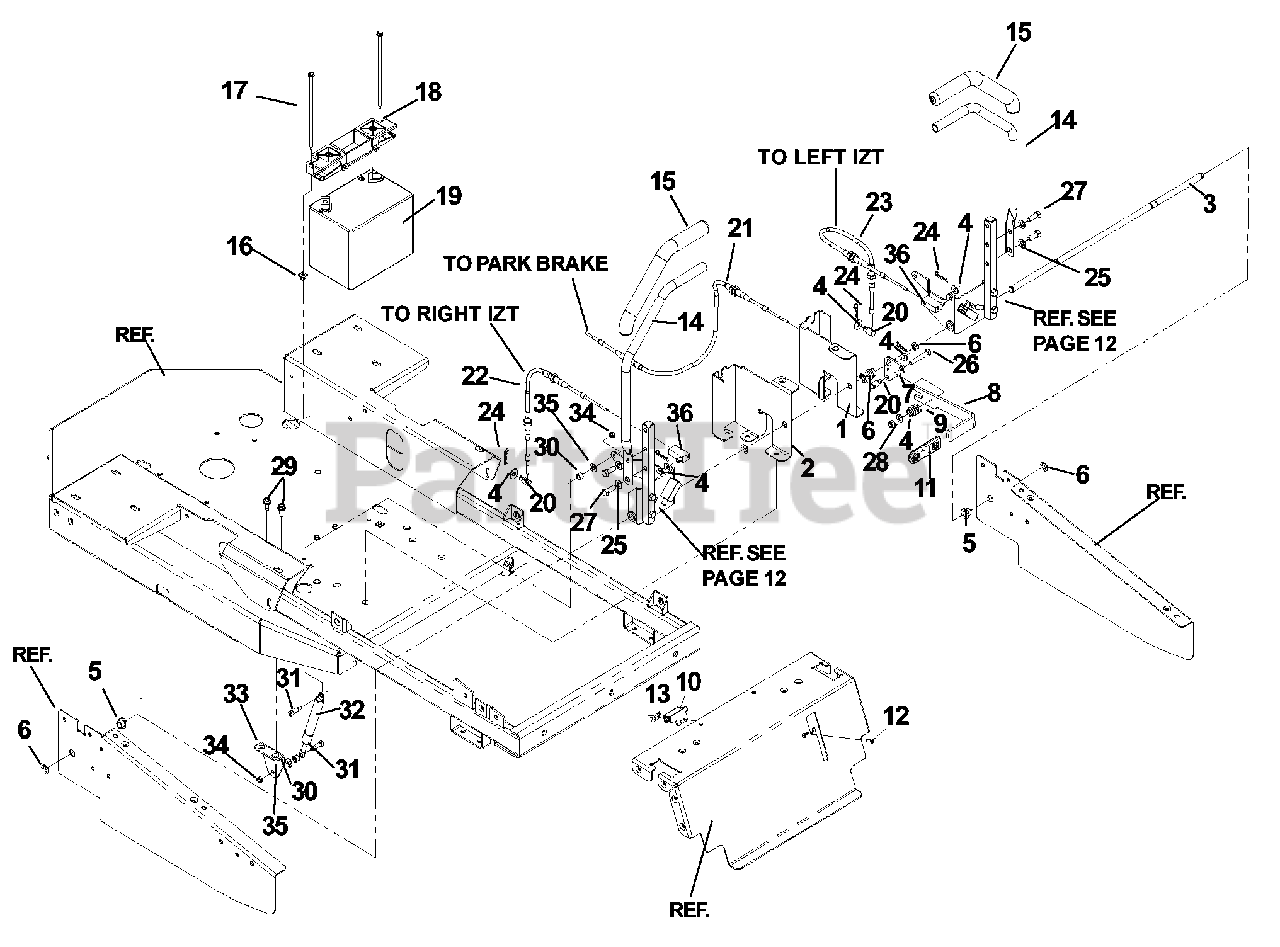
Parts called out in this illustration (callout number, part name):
1	BATTERY SUPPORT, LEFT
2	BATTERY SUPPORT, RIGHT
3	CONTROL PIVOT SHAFT
4	WASHER, 5/16 FLAT
5	BUSHING, NYLON FLANGED
6	E-RING, 1/2"
7	BRAKE LEVER
8	UPPER BRAKE LEVER
10	SWITCH N.C.
11	GRIP, PARK BRAKE
12	SCREW, #10-24 X 5/8 MACH.
13	TAPPED PLATE
14	CONTROL LEVER
15	DRIVE LEVER CUSHION
16	PUSH NUT, NYLON
17	BOLT, 1/4-20 X 7 1/2
18	BATTERY HOLD DOWN
19	BATTERY, DRY
20	CONTROL SWIVEL
21	CABLE, BRAKE
22	CABLE, RIGHT
23	CABLE, LEFT
24	COTTER, HAIRPIN
25	WASHER, 3/8 SPRING
26	HCS 5/16C X 2
27	HCS 3/8C X 1
28	NUT, 5/16C NYLOC
29	BOLT 5/16-18 X 3/4, THREAD FORMING
31	BOLT 5/16C X 5/8, SHLD
33	BRACKET, DAMPENER
34	NUT 1/4C, THIN NYLOC
36	UPPER CABLE END
